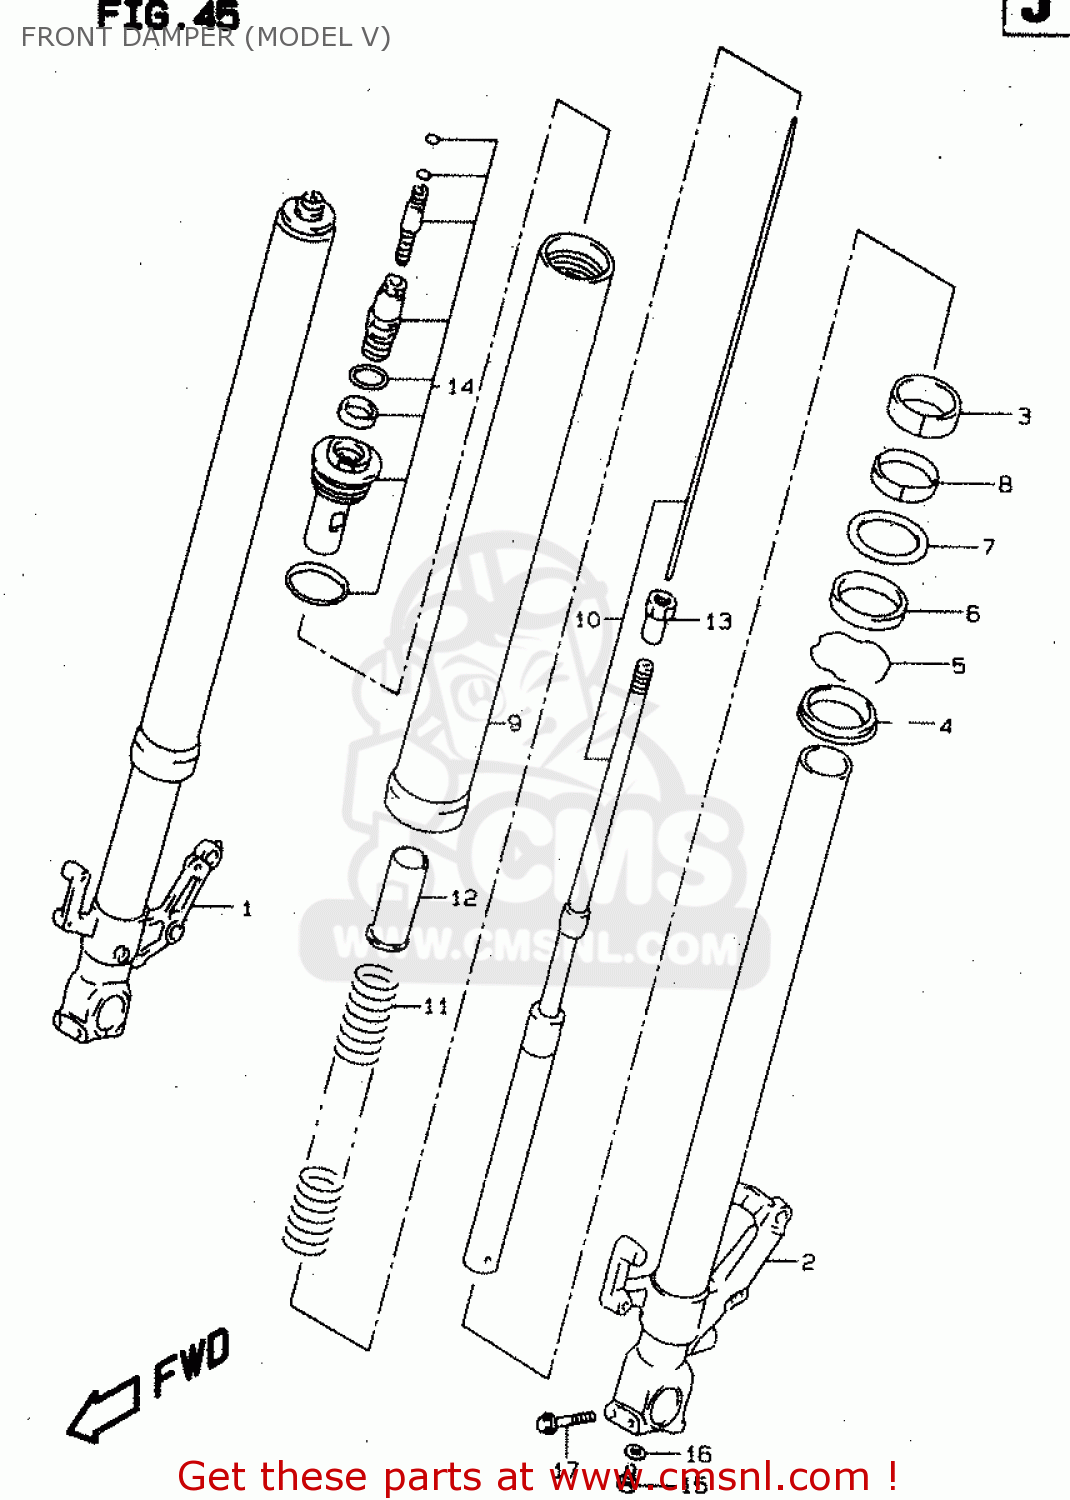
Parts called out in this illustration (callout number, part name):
1	TUBE,INNER,R
2	TUBE,INNER,L
3	PISTON
4	SEAL,DUST
5	RING,STOPPER
6	SEAL,OIL
7	WASHER
8	METAL,SLIDE
9	TUBE,OUTER
10	CYLINDER
11	SPRING,FRONT
12	SPACER
13	NUT,PISTON ROD
14	CAP,FORK
15	BOLT,OIL LOCK PIECE,12X22
16	GASKET,CYLINDER (NAS)
17	BOLT
